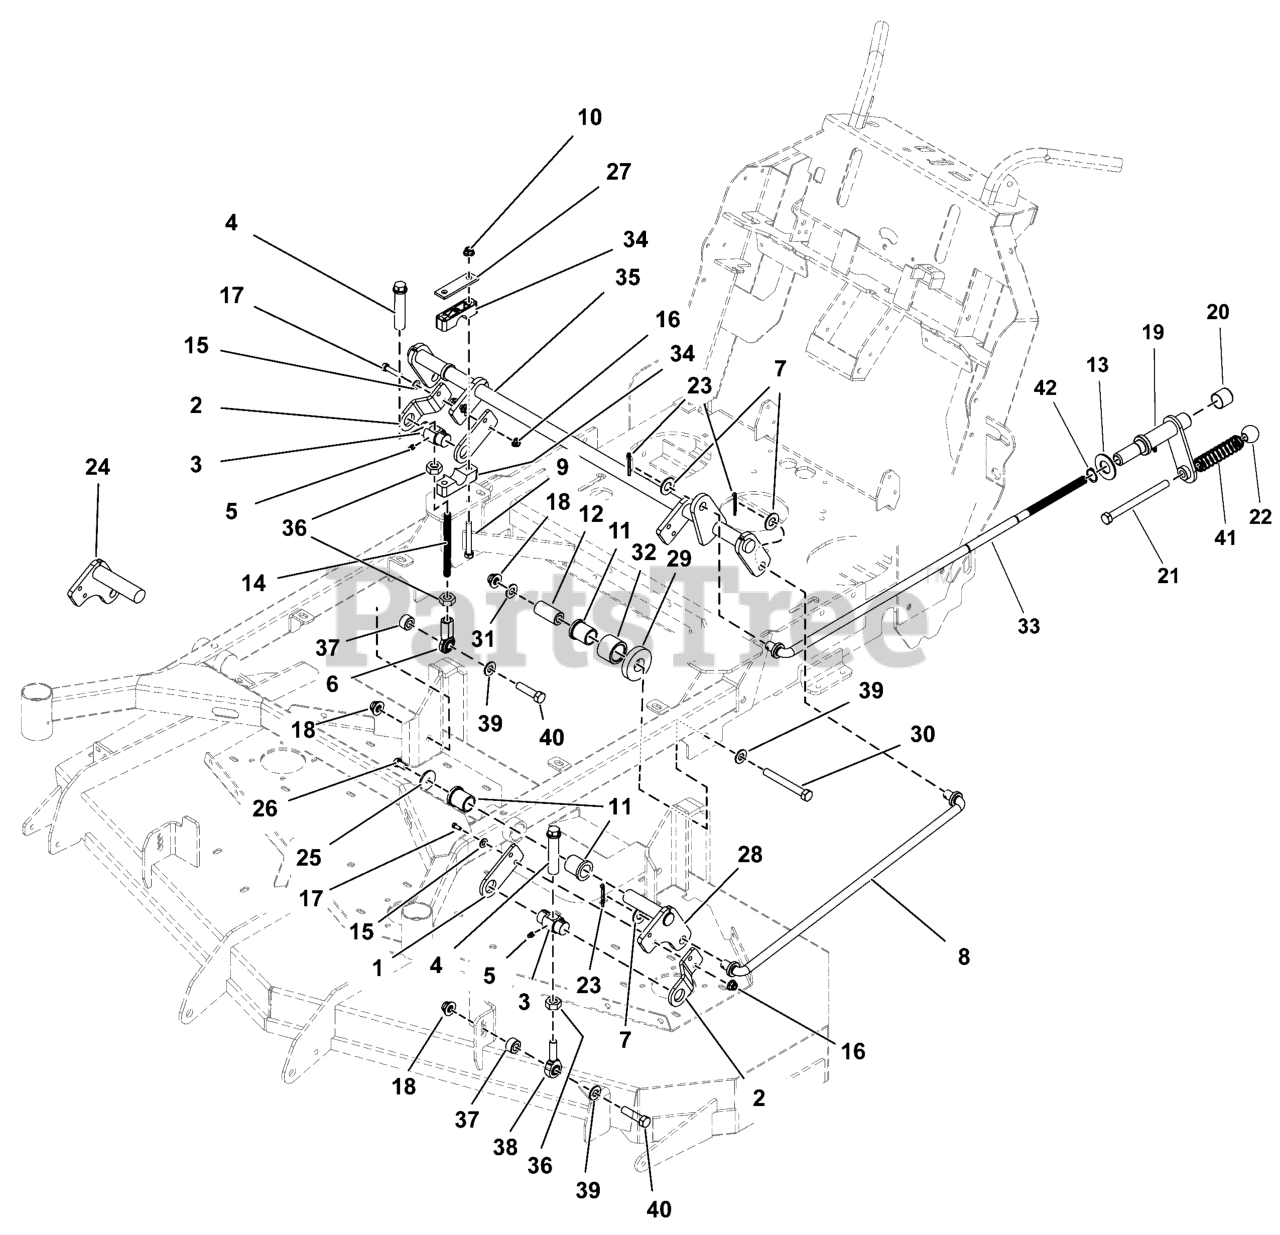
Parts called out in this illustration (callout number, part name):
1	BRACKET, INNER TRUNION MNT - BLK
2	BRACKET, OUTER TRUNION MNT - BLK
3	PIVOT, DECK LIFT TRUNION, GREASABLE
4	ADJUSTER, HEIGHT
5	GREASE FITTING, 1/4-28 Straight
6	JOINT-BALL .500-20 THD .500ID, CLR ZINC
7	WASHER, 5/8" SAE
8	ROD, DECK LIFT TIMING, 48-52
9	BOLT, 3/8-16 X 2-3/4" GD5 CZ
10	NUT, 3/8 - 16 HEX NYLOCK FLANGE
11	BUSHING, FLANGE
12	SPACER, .52 X 1.00 X 2.09 - SS
13	WASHER-1.00 HYDRO CUT
14	ROD, 1/2-20 X 5.50 TFL, CZ
15	WASHER, 3/8 SAE
16	NUT, 3/8 - 16 HEX NYLOCK FLANGE
17	BOLT, 3/8-16 X 1-1/2" GD5 CZ
18	NUT, Hex Flange, Nylock, 1/2-13
19	CRANK, HANDLE, W45
20	CAP, VINYL, 1.062 X 1.00 BLK
21	BOLT, 1/2-13 X 6" GD5 YZ
22	KNOB, PLASTIC, 1/2-13
23	PIN, COTTER, 1/8 X 1-1/4
25	WASHER, .390 X 1.50 X .109, YZ
26	BOLT, 3/8-16 X 3/4, PLT W/PATCH
27	PLATE, PIVOT BLOCK SUPPORT - BLK
28	WELD, DECK LIFT LEVER, LH - BLK
29	WASHER, FRICTION
30	BOLT, 1/2-13 X 3-1/4, HEX HD, GD5, CZ (SV)
31	WASHER, 1/2" USSZ
32	ROLLER, DECK HEIGHT
33	ROD, DECK HEIGHT
34	PIVOT BLOCK, PLASTIC
35	WELD, SHAFT, DECK LIFT, SW35 - BLK
36	NUT, 1/2-20 Hex Jam
37	WASHER, .515 X 1.00 X .25", CZ
38	BALL JOINT, 1/2-20, RH, MALE, METAL RACE
39	WASHER, 1/2 SAE
40	BOLT, 1/2-13 X 2" GD5 CZ
41	SPRING, FORWARD RETURN, FW15
42	SNAP RING, EXTERNAL, 15/16" SHAFT
